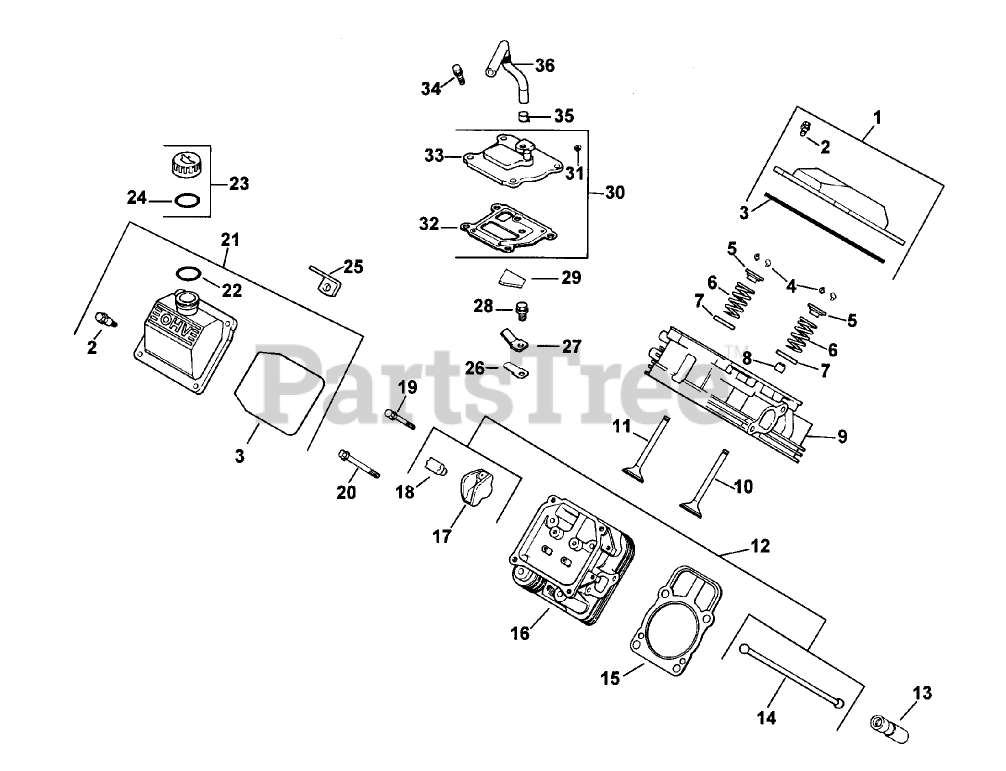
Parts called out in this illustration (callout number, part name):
1	Kit, valve cover-plain (Includes 2,3)
2	Screw-Shoulder (M6x1.0x30)
3	O-Ring
4	RETAINER KIT
5	CAP-SPRING, VALVE
6	SPRING-VALVE
7	RETAINER-SPRING
8	Seal-Stem, Valve
9	#1 Cylinder Head ASM
10	VALVE-INTAKE (STD)
11	VALVE-EXHAUST (STD)
12	Kit, valve train (Includes 14, 17, 18)
13	Lifter-Valve
14	ROD-PUSH
15	Gasket, cylinder head
16	Head assembly, #2 cylinder
17	ARM-ROCKER
18	Pivot-Arm, Rocker
19	SCREW-FLANGE (M6X1.0X34)
20	SCREW-FLANGE (M10X1.5X90)
21	Kit, valve cover-oil fill (Includes 2, 3, 22)
22	O-Ring
23	Kit, oil fill cap (Includes 24)
24	O-Ring
25	STRAP-LIFTING
26	REED-BREATHER
27	Retainer-Reed, Breather
28	SCREW-HHFTF (M5X.80X10)
29	Filter-Breather
30	Kit, breather (Includes 31-33)
31	Plug
32	Gasket-Breather
33	Cover-Breather
34	SCREW-HHFTF (M6X1.0X20)
35	Clamp
36	Hose-Breather
